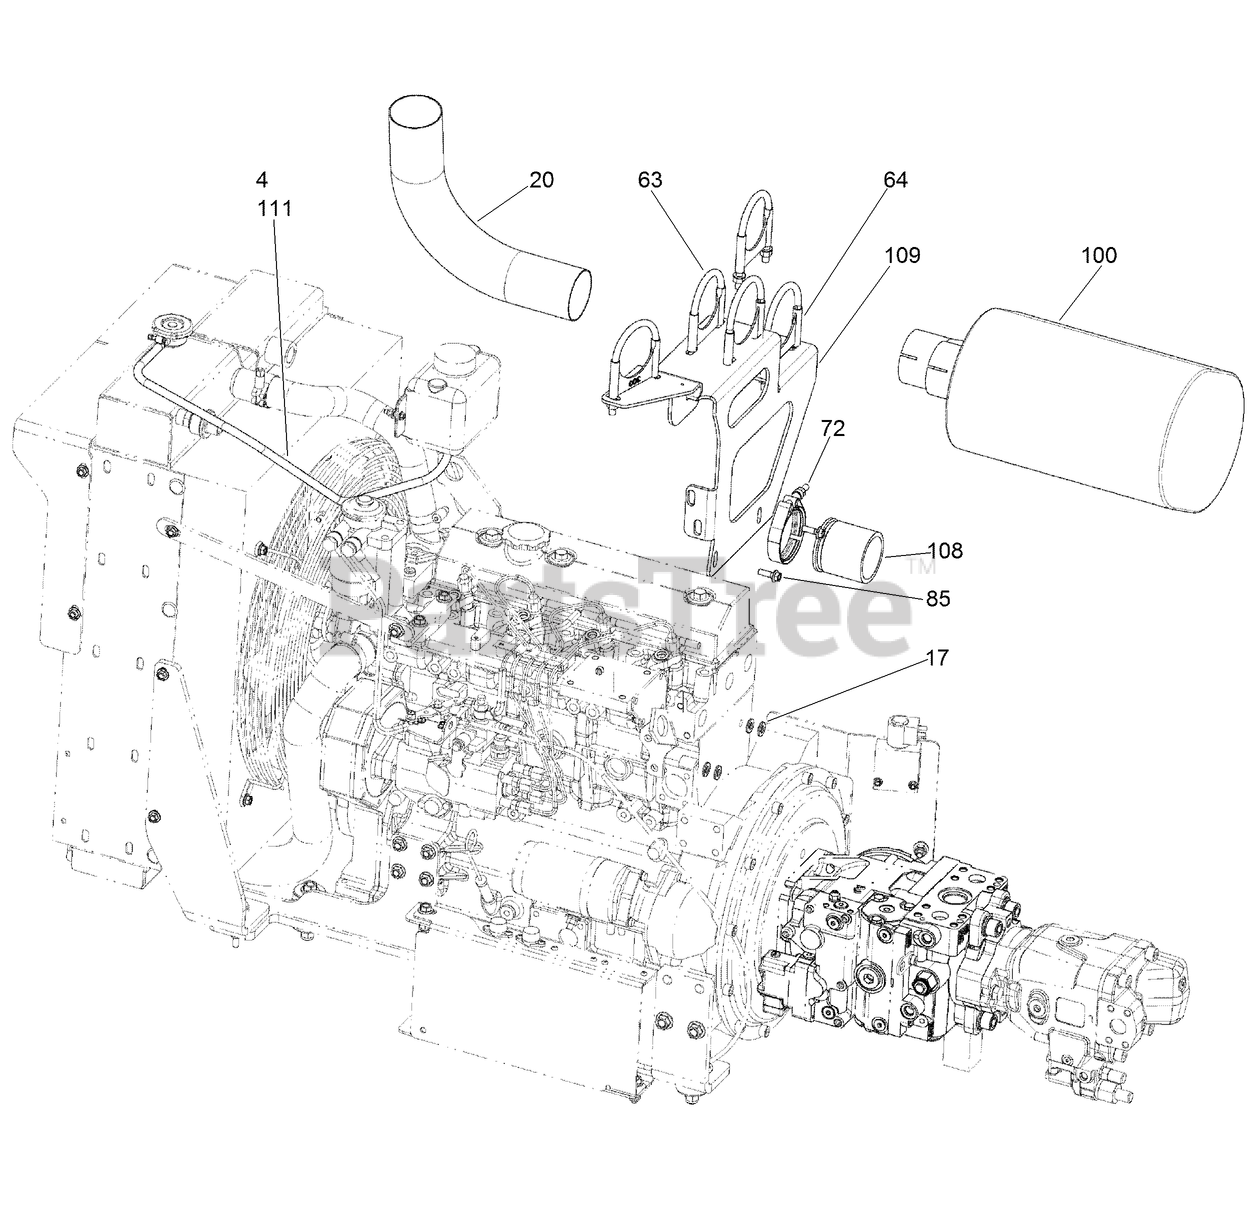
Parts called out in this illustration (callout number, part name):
4	CLAMP - Hose Type M # 06
17	WASHER-FLAT
20	ELBOW - Exhaust 3.00 x 90
63	CLAMP-GUILLOTINE
64	CLAMP-GUILLOTINE
85	SCREW-FLANGE
100	ASSEMBLY - Muffler
108	FLANGE-ADAPTER, TURBO
109	ASSEMBLY - Muffler Mount
111	OVERFLOW LINE - 3/8 ID x 32 Length
